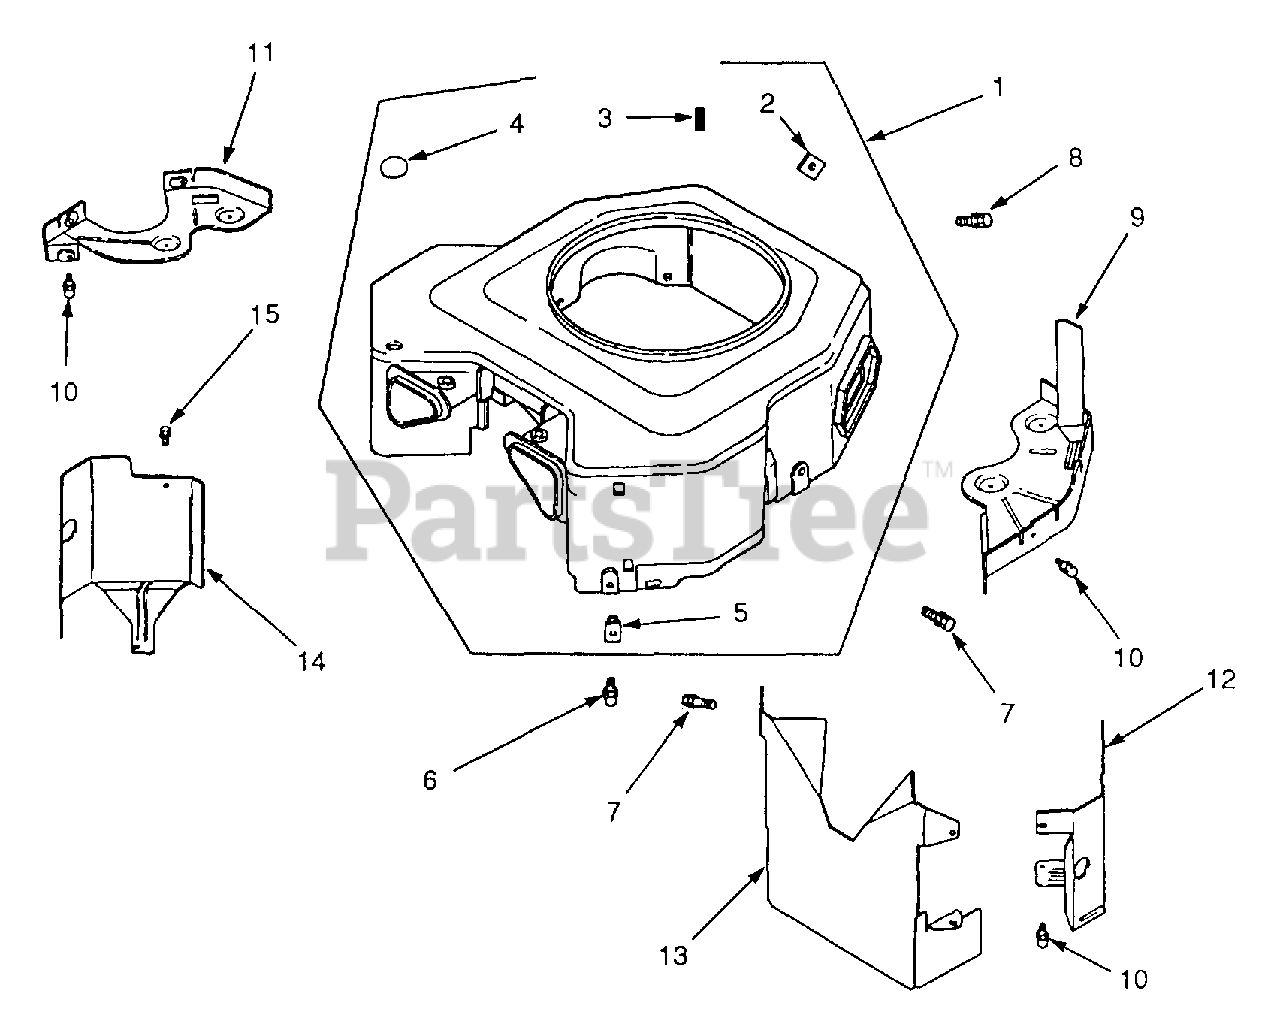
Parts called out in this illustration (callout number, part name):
1	Housing, Blower
2	Nut, Plastic
4	Plug, Button, 9/16
5	Nut, Plastic
6	Screw, Hex Flange, M5 x 0.8 x 20
7	Screw, Hex Flange, M5 x 0.8 x 16
8	Screw, Hex Flange, M5 x 0.8 x 16
9	Plate, Backing - #2 Side
10	Screw, Hex Flange, M6 x 1.0 x 16
11	Plate, Backing - #1 Side
12	Baffle, Cylinder Barrel - #2 Side
13	Baffle, Valley
14	Baffle, Cylinder Barrel - #1 Side
15	Screw, Hex Flange, M5 x 0.8 x 10
